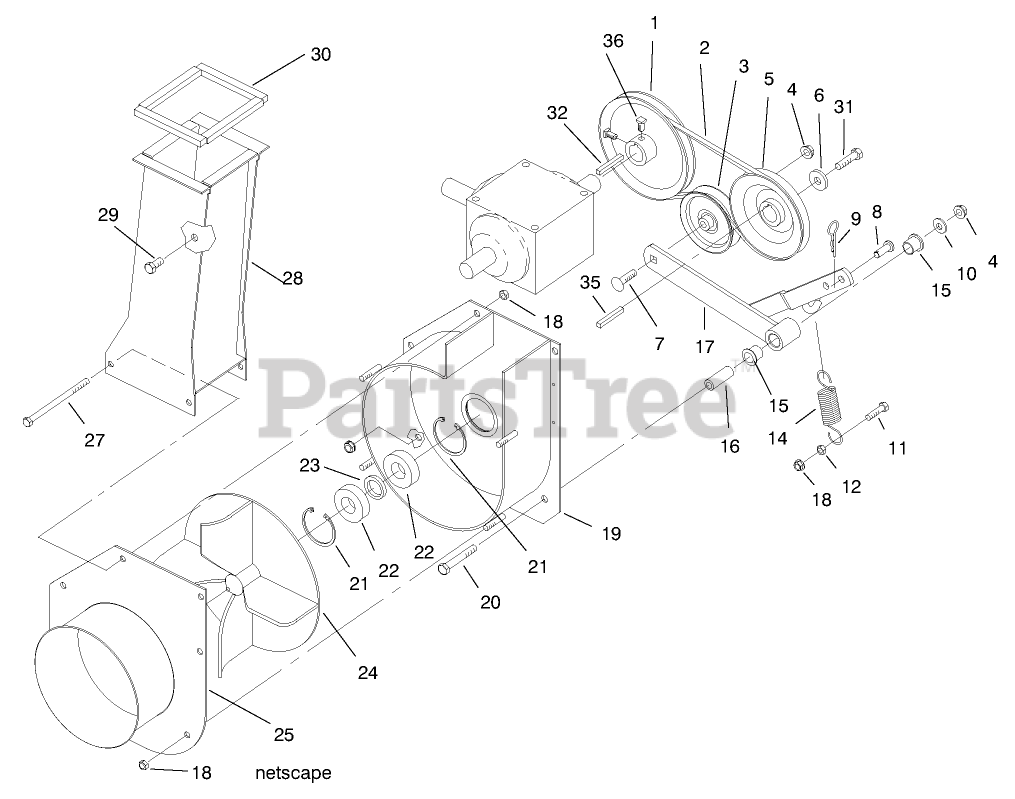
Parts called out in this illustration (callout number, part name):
1	PULLEY-GEARBOX
2	V-BELT
3	PULLEY-IDLER
4	NUT-HF
5	PULLEY - IMPELLER B
6	WASHER-THRUST, PLAIN
7	SCREW-CARR
8	PIN-CLEVIS
9	PIN-HAIR
10	WASHER-FLAT
11	SCREW-HH
12	NUT-HEX
14	SPRING-EXTENSION
15	BUSHING-FLANGE
16	SPACER
17	Idler Arm
18	NUT-HF
19	Housing
20	SCREW-HH
21	RING-SNAP
22	BEARING-BALL
23	SPACER-BEARING
24	Impeller ASM
25	Cover
27	SCREW-HH
28	Impeller Chute
29	SCREW-HH
30	STRIP - FOAM
31	SCREW-HH
32	KEY-SQUARE
35	KEY-SQUARE
36	SCREW-SET, SQH
